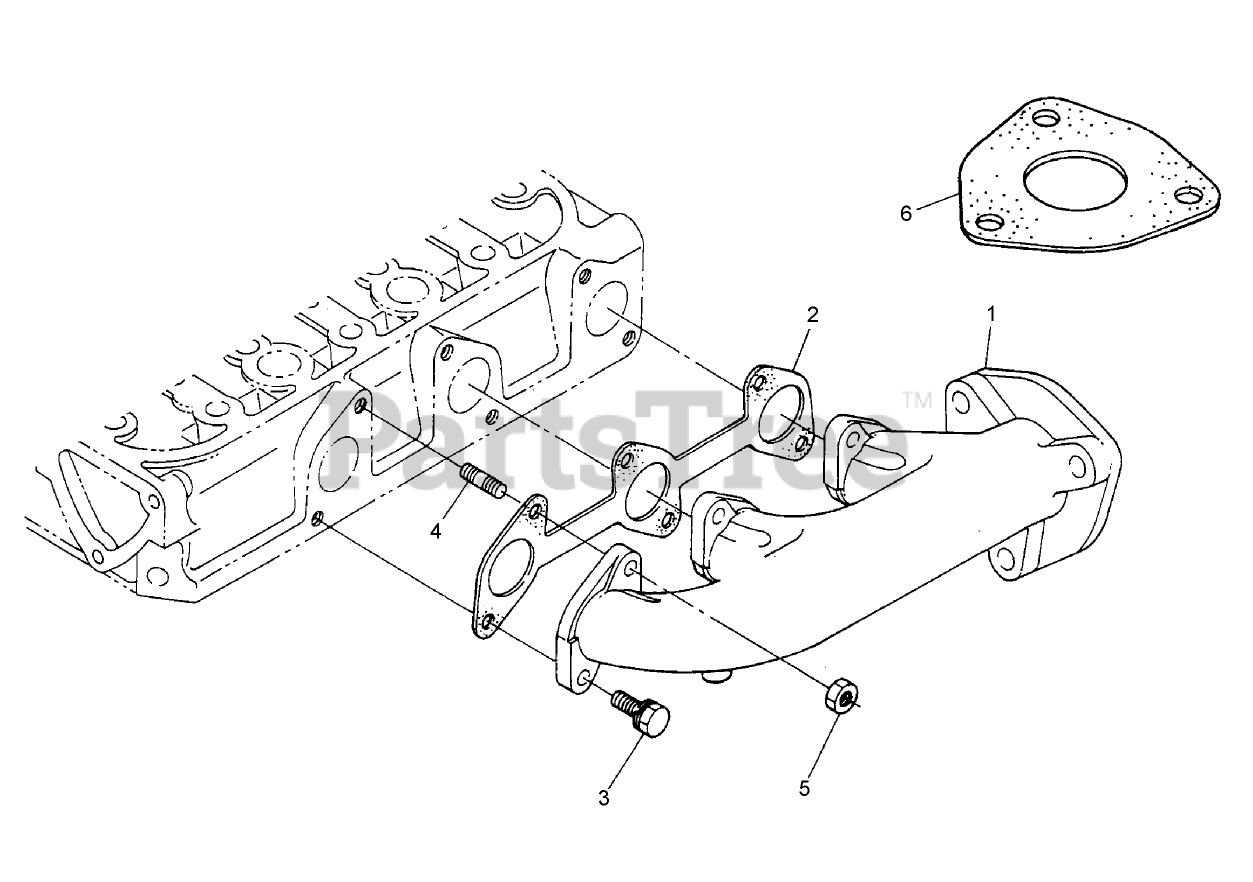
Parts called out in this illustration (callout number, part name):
1	MANIFOLD-EXHAUST
2	GASKET
6	GASKET-MUFFLER
